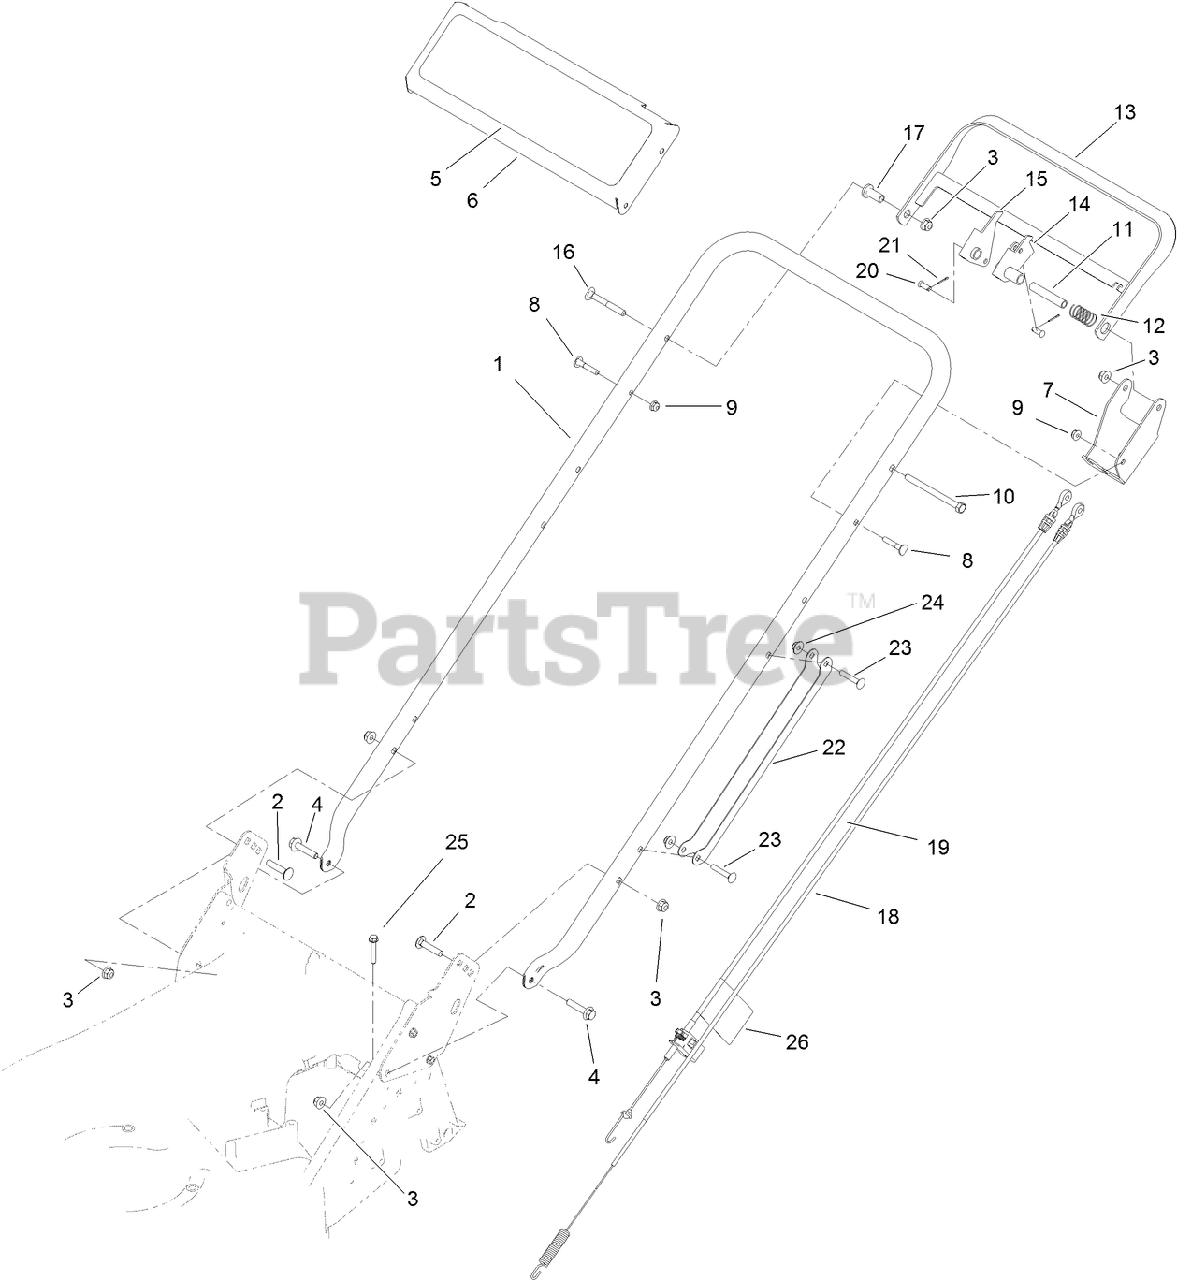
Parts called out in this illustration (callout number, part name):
1	HANDLE
2	BOLT-CARR
3	NUT-HF, NI
4	SCREW-HHF
5	DECAL-TORO, COMMERCIAL
6	PANEL-CONTROL
7	BRACKET-CONTROL
8	SCREW-HANDLE
9	NUT-HF
10	SCREW-HH
11	SPACER
12	SPRING-CONTROL
13	BAR-CONTROL
14	LEVER-CONTROL
15	LEVER-TRACTION
16	SCREW-HANDLE
17	SPACER-FLANGE
18	CABLE-BBC
19	CABLE-TRACTION, BBC
20	PIN-CABLE
21	PIN-COTTER
22	GUARD-CABLE, HANDLE
23	SCREW-CARR
24	NUT-HF
25	SCREW-HWH
